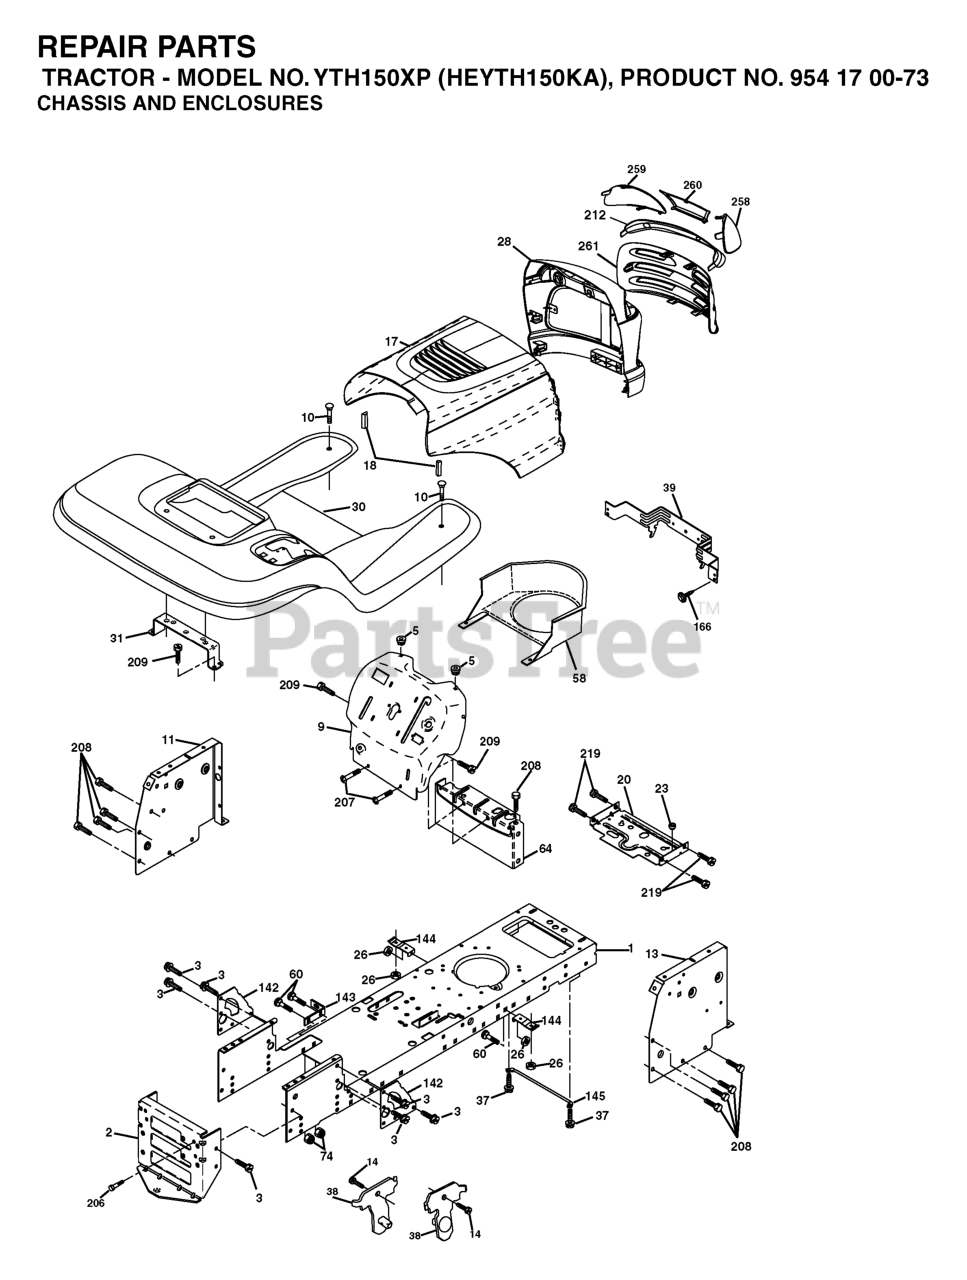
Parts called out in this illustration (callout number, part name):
1	CHASSIS STAMPING
2	DRAWBAR, 12GA
3	SCREW 3/8-16X3/4
5	BUMPER.RUBBER.HOOD
9	DASH
10	BOLT D
11	PANEL.DASH.LH.LTX
13	PANEL ASM, DASH RH
17	HOOD
18	BUMPER.HOOD.LARGE.1.75"
20	PLATE MTG.BATTERY/FUEL TANK
23	BUSHING.SNAP.NYL.BLK.
26	NUT
30	FENDER FOOTREST
31	BRACKET.SUPPORT.FENDER
37	Screw 5/16-18 x 1/2 Hex, Self Tapping 5/16-18 x 1/2
38	BRACKET.ASM.PIVOT.MOWER.REAR
39	BRACKET PIVOT LASER
58	DUCT, INTAKE AIR
60	Bolt - Rd. Hd. Sq. Neckiage 3/8 16 x 3/4
64	DASH LOWER
142	PLATE REINFORCEMENT
143	BRACKET, SWAY BAR
144	BRKT, FOOT REST
145	ROD PIVOT CHASSIS/HOOD
166	SCREW
206	SHOULDER BOLT 5/16-18TT
207	SCREW, 5/16-18 X 1/2
208	SCREW 3/8-16X1/2
209	SCREW, 3/8-16X3/4
212	INSERT.LENS.REFLECTIVE
219	SCREW
258	LENS LH
259	LENS LH
260	COVER.LENS.HUSQ.LASER
